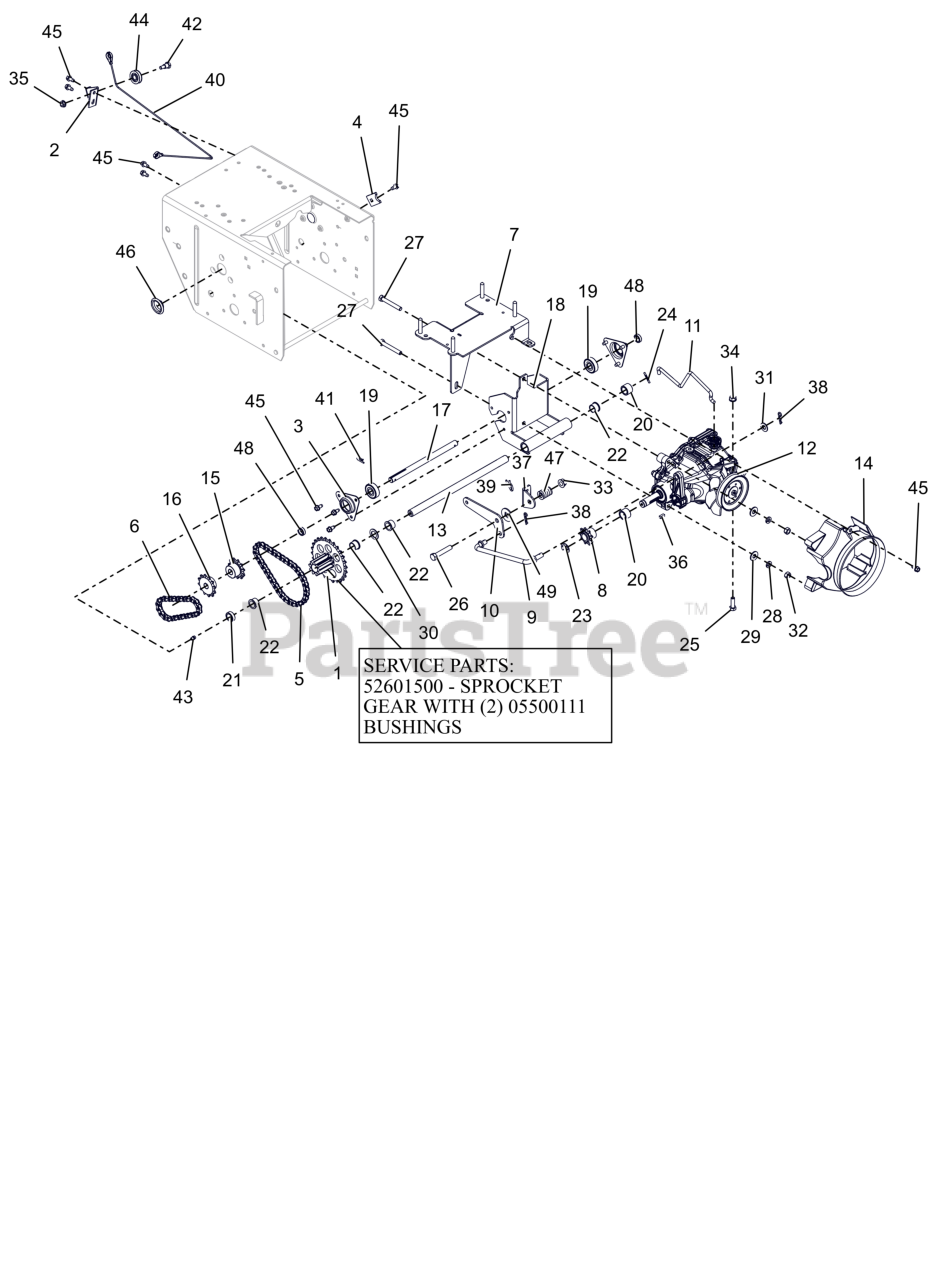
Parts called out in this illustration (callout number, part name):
1	PINION & SPROCKET
1	PINION & SPROCKET W/BUSHINGS
2	BRACKET, CABLE PULLEY
3	FLANGE, BEARING
4	TAB, ANTI ROTATION
5	ROLLER CHAIN #41 - 34 PITCHES
6	CHAIN-ROLLER #41X26 PITCHES
7	BRACKET, HYDROSTATIC TRANS XLG
8	SPROCKET, PINION 9T W/KEY
9	ROD, HYDRO TRANS SHIFT
10	PIVOT, HYDRO TRANS SHIFT
11	ROD, HYDRO BYPASS
12	TRANSMISSION, HYDROSTATIC
13	SHAFT, PINION - HARDENED
14	SHROUD, HYDROGEAR RT-310
15	SPROCKET, 11 TOOTH
16	SPROCKET, 12 TOOTH
17	SHAFT, REDUCTION HEAT TREATED
18	SUPPORT, REDUCTION-BWT
19	BRG-BALL .500X1.38X.437
20	SPACER, .635X.880X.611
21	BSHG-SLV, .635X.880X.305
22	BSHG-FLG .625X.750X.500X.875
23	RG-RTNG-EXT .625X.042
24	@PIN-GRV .125X1.00 TP E ALLOY
25	BLT,HEX .31-18X1.00 G5 ZCC
26	BLT,HEX .38-16X2.00 G5 ZCC
27	BLT, HEX .31-18X2.25 G5 ZCC
28	WSHR, LK-HVY .312X.097 ZCC
29	WSHR,FLT .375X.875X.083 ZCC
30	WSHR, FLT .630X1.005X.062 ZCC
31	WSHR,FLT .406X.812X.065 ZCC
32	NUT, HEX .312-18 ZCC
33	NUT-LK-TOP-FLG .38-16 ZC120
34	NUT-LK-TOP-FLG .312-18 GF ZCC
35	NUT-LK-TOP-FLG .250-20 GF ZCC
36	KEY-SQ .187 X .50 X .187
37	BRACKET, HYDRO SHIFT PIVOT
38	PIN, HAIR #213 .08X1.19 ZCC
39	PIN, SPRING CLIP
40	CABLE, TRACTION, HYDRO PRO
41	CLIP, SPRING
42	BOLT, SHLDR -.375 X .375 X .25-20
43	ZERK,FITTING .25X.125 DRIVE IN
44	PULLEY, CABLE
45	SCR-TAP .25-20X.50 HWH ZCC
46	PLUG, HOLE - 1.125"
47	SG-COMP .187X.56X1.62
48	SPCR, SLV
49	FRICTION WASHER
